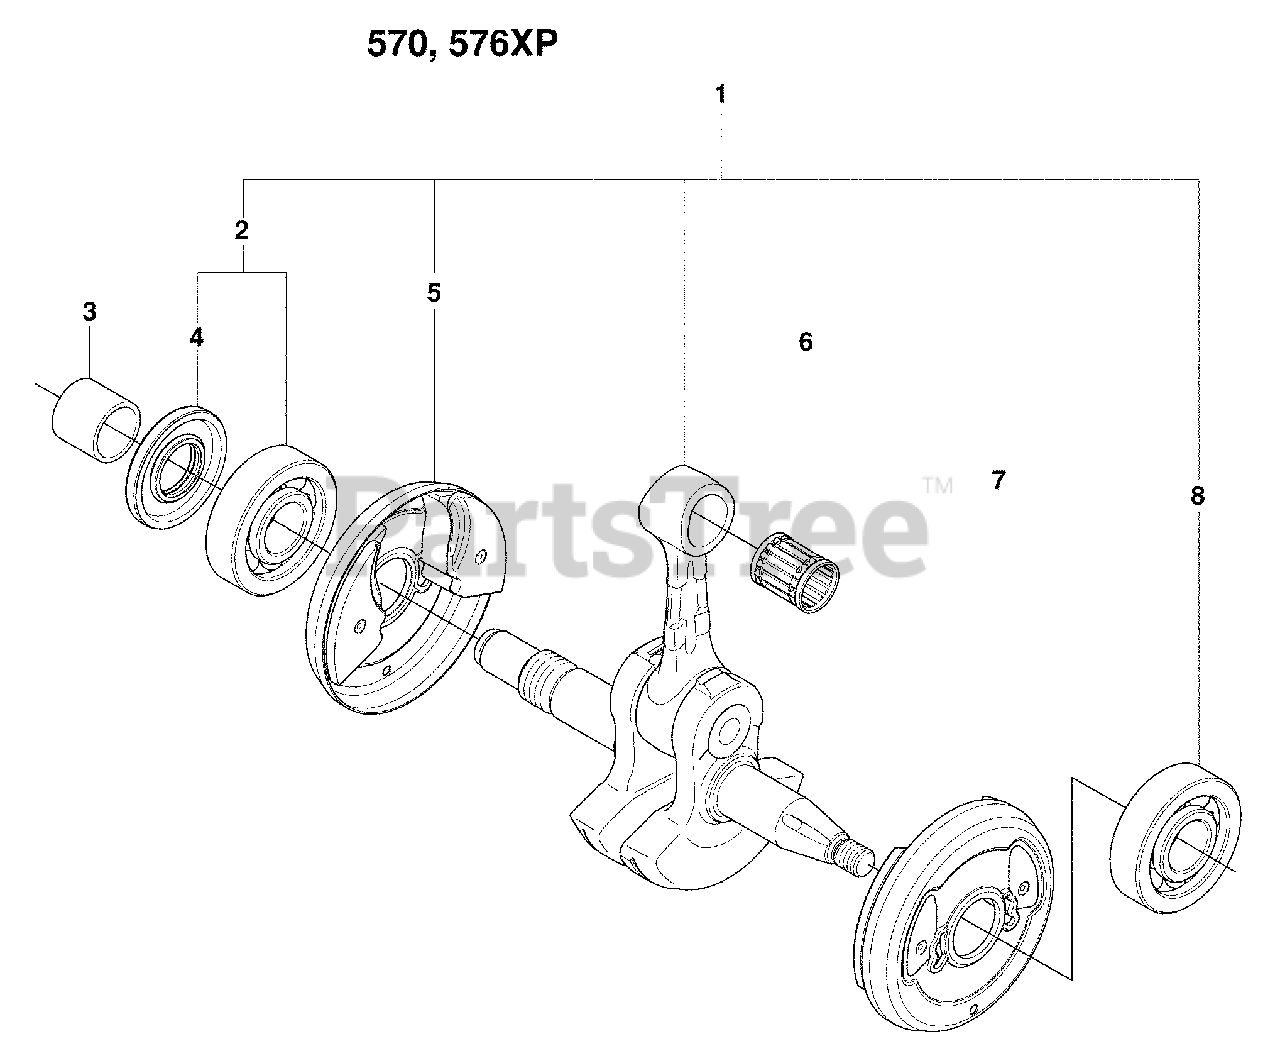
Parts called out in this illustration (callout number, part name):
1	Crankshaft
1	Crankshaft Assembly
2	Ball Bearing
4	Radial Seal
6	Needle Bearing Piston Pin, 12 X 1
8	Ball Bearing, 6202C3 SK
8	Ball Bearing
